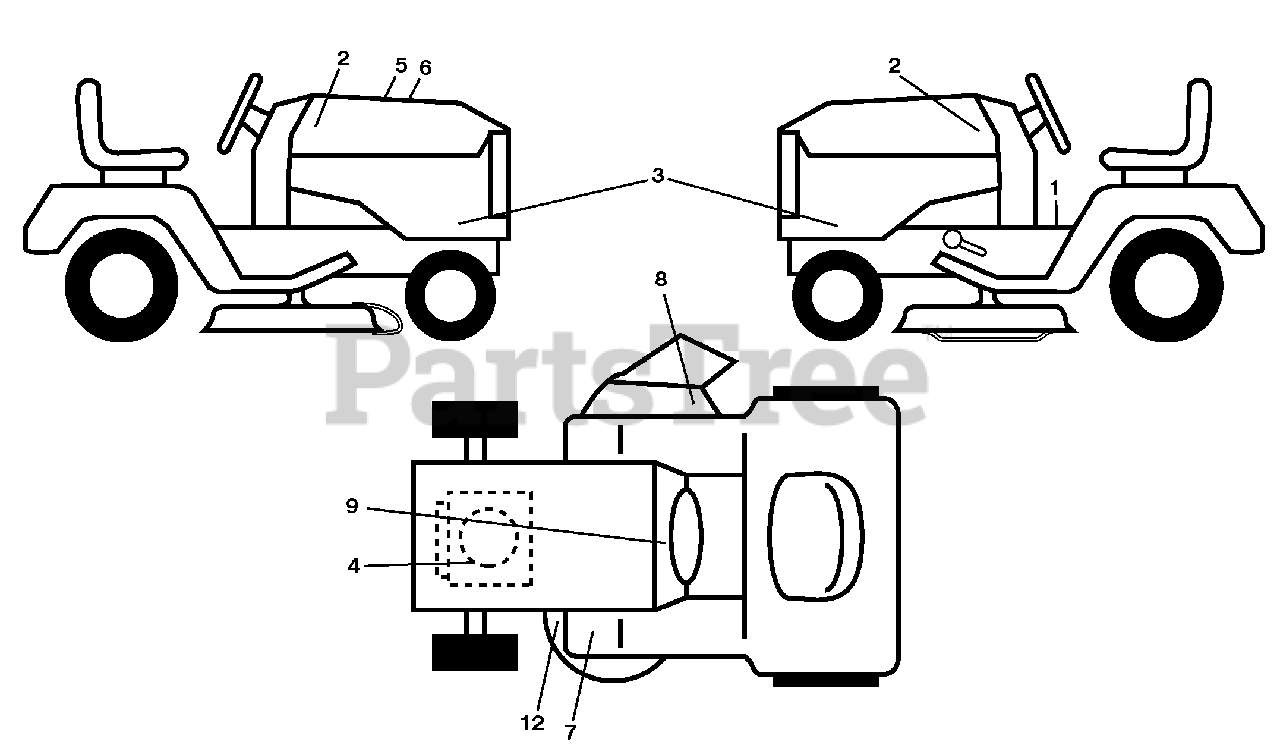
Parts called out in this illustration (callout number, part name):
1	Decal, Operators
2	Decal, Badge
3	Decal, Panel SD
4	Decal, Eng. HP
5	Decal, Customer Respons.
6	Decal, Replacement
7	Decal, Pedal Husq. Crown
8	Decal Mower Warn Keep Hand away
9	Decal, Battery Dnge/Poi
12	Decal, Mower V-Belt Schematic
